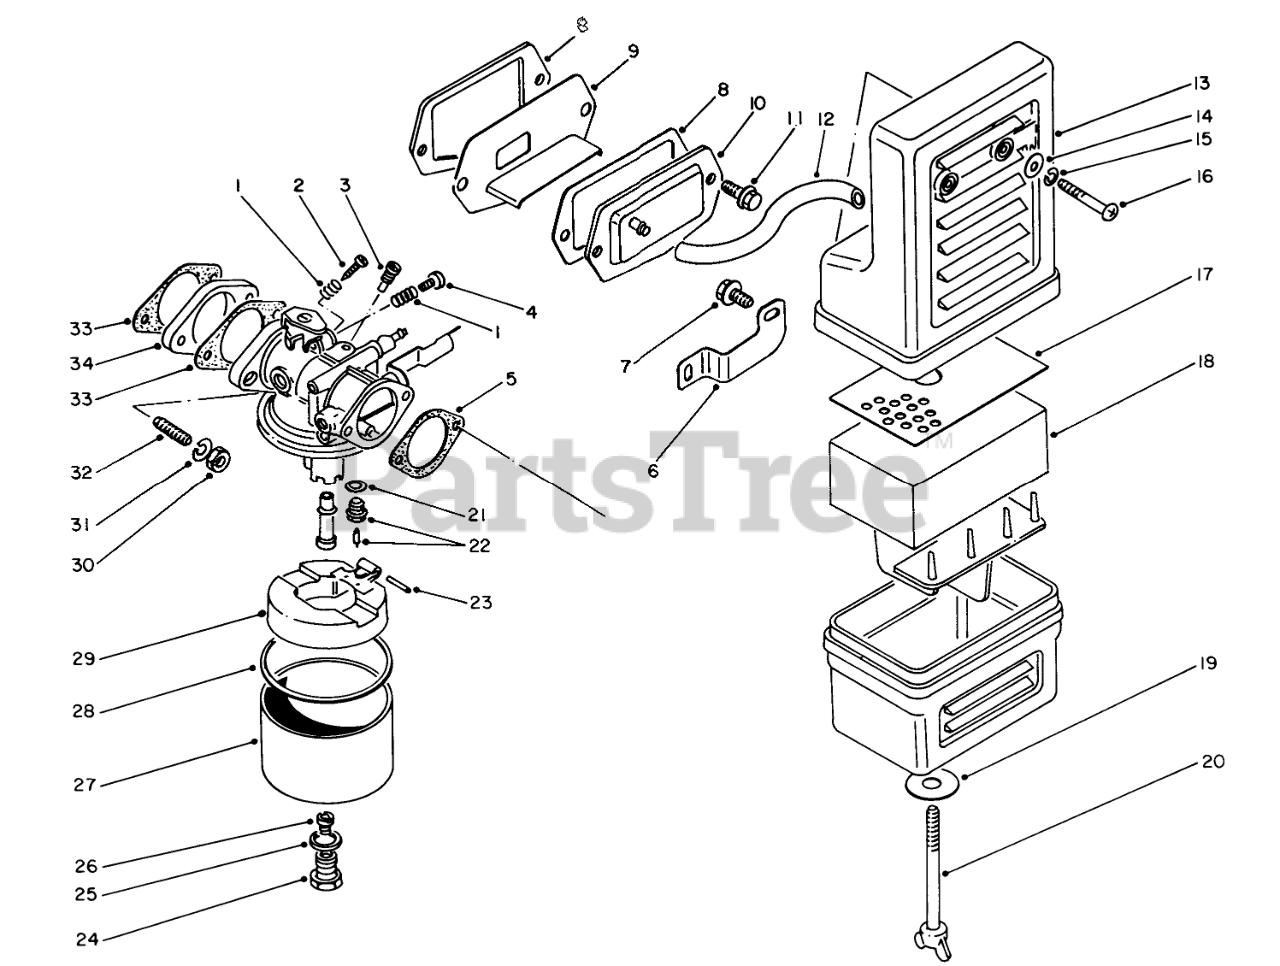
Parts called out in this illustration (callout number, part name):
1	Spring
2	ADJUSTER
3	Jet-Pilot (40)
4	Screw
5	AIR CLEANER GASKET
6	AIR CLEANER BRKT
8	Gasket
9	Reed Valve Assembly
10	Cap-Breather
13	Cleaner Assembly-Air (Incl. Ref. #17-20)
14	WASHER
15	Washer
16	SCREW
17	Holder
18	FILTER
19	WASHER
20	Bolt-Wing
21	GASKET
22	NEEDLE VALVE
25	Gasket
26	MAIN JET
27	Carburetor Assembly (Incl. Ref. #21-26 & 28-30)
28	GASKET
29	Float
31	Lockwasher
32	Stud Bolt
33	Gasket
34	INSULATOR
